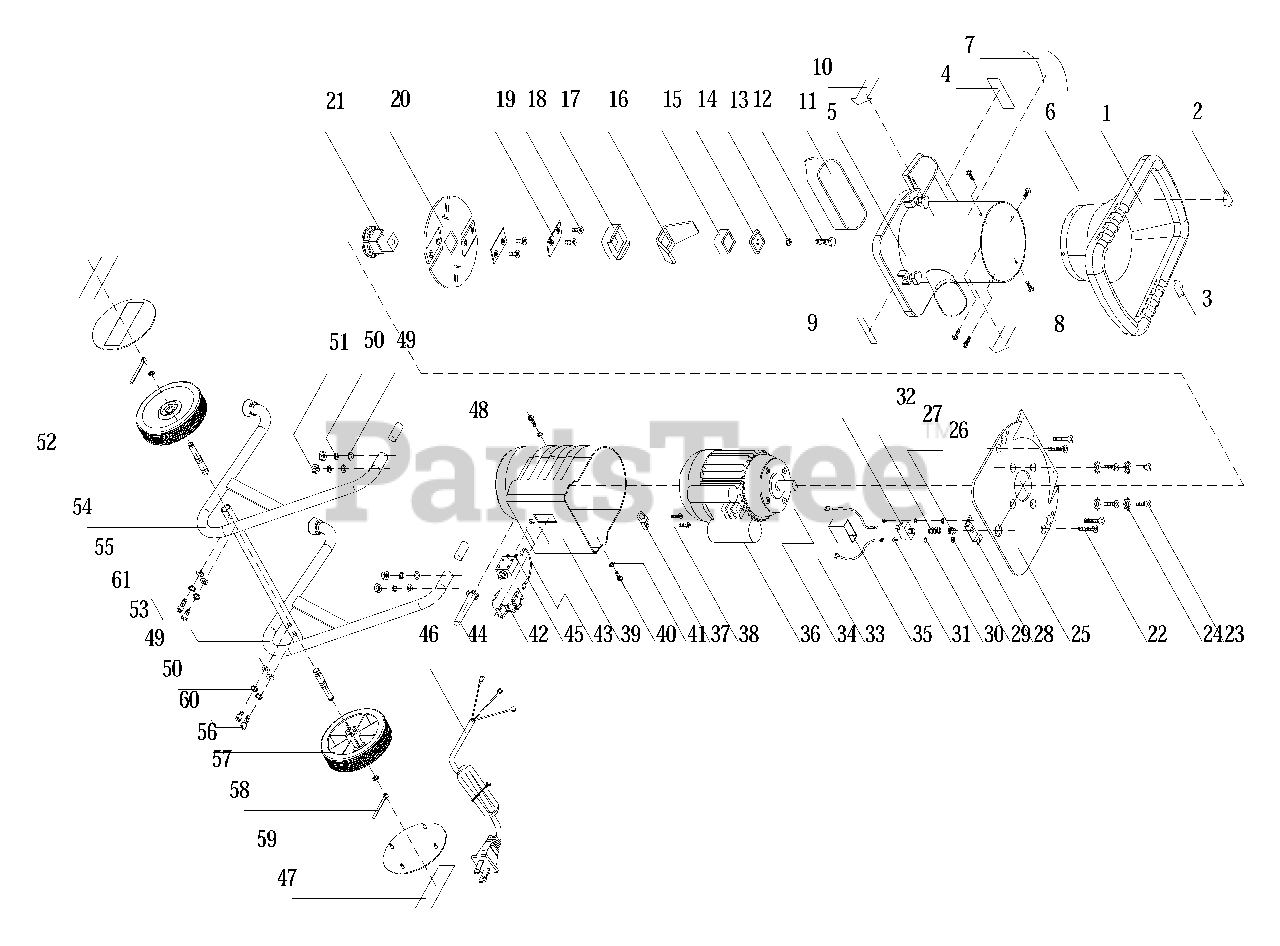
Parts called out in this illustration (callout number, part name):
1	TOP HOPPER ASS'Y
2	LABEL (LEAVES)
3	LABEL (BRANCH)
4	LABEL (WARNING)
5	BODY ASS'Y
7	LABEL (BRAND)
8	LABEL (BRANCHES)(R)
9	LABEL (WARNING)
10	LABEL (BRANCHES)(L)
11	RESTRAINING COVER
12	HEX SCREW
13	SPRING WASHER M10
14	CUTTER CLAMP
15	SQUARE BUSH
17	V-CUTTER BASE
18	SCREW M8X15
19	CUTTER (BLADE)
20	CUTTER BASE
21	CUTTER BUSH
24	SPRING WASHER M8
25	BRACKET CLAMP ASS'Y
26	DUSTPROOF RUBBER
27	RESTRAINNIG SPRING
28	SWITCH HOLDER
29	FLAT WASHER
30	SPRING WASHER M4
32	CUT-OUT SWITCH
33	INTERNAL WIRE I
34	INTERNAL WIRE II
35	SWITCH COVER
36	MOTOR ASS'Y
37	CORD CLAMP
39	MOTOR COVER
41	FLAT WASHER
42	ON/OFF SWITCH
43	INTERNAL WIRE
44	CORD GUARD
45	THERMOSTAT
46	POWER CORD
47	TALON LABEL
48	STRENGTEN SHAFT
49	FLAT WASHER
50	SPRING WASHER
51	HEX NUT
52	WHEEL SHAFT
53	RIGHT HOLDER ASS'Y
54	LEFT HOLDER ASS'Y
55	CONNECTING TUBE
57	FLAT WASHER
58	SPLIT PIN
59	WHEEL COVER
60	HEX SCREW
61	HEX SCREW
